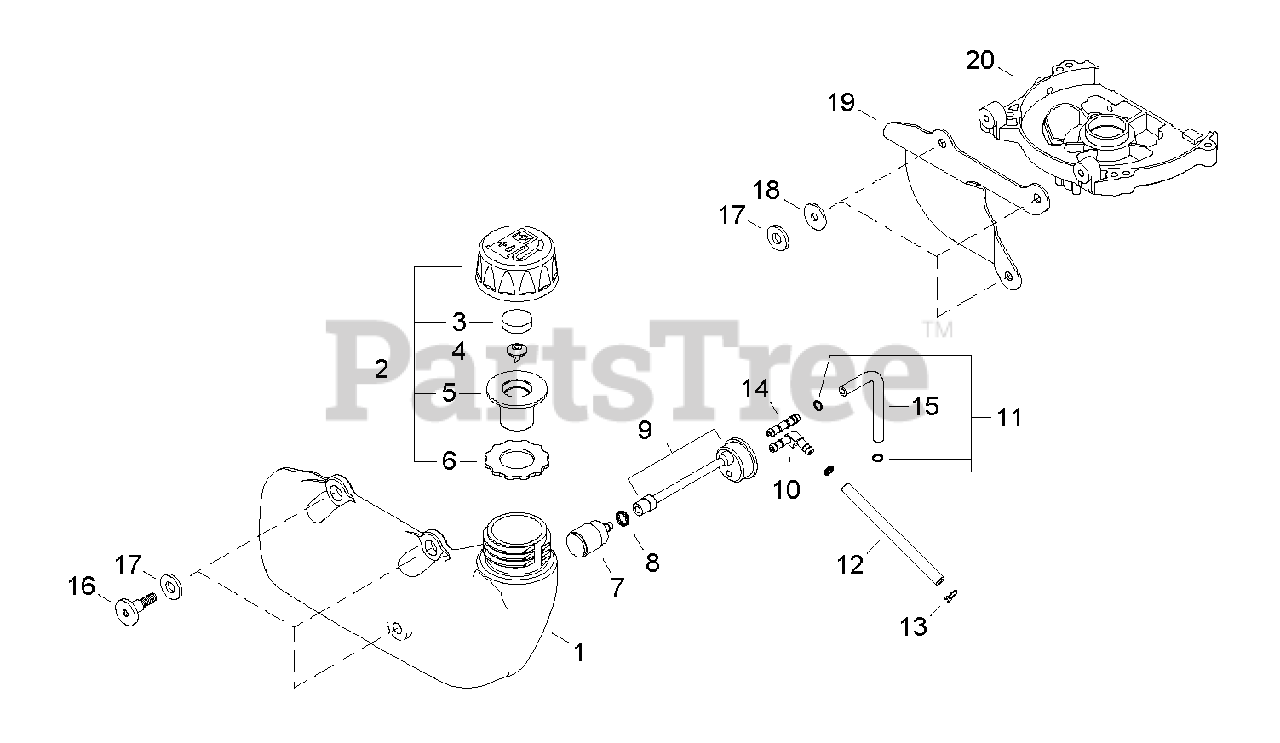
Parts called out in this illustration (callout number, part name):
1	TANK, FUEL
2	CAP, FUEL
3	PACKING, VENT
4	VENT ASSY
5	HOLDER, VENT
6	GASKET, FUEL CAP
7	FILTER, FUEL 125-528
9	GROMMET, FUEL WITH PIPE
10	CONNECTOR, PIPE
11	CLIP Ø6
12	PIPE, FUEL RETURN
13	CLIP, SPRING Ø5.2
14	CONNECTOR, PIPE
15	PIPE, FUEL
16	BOLT, ADHESIVE 5
17	WASHER 6
18	WASHER 5
19	SHIELD, HEAT
20	CRANKCASE ASSY, M
